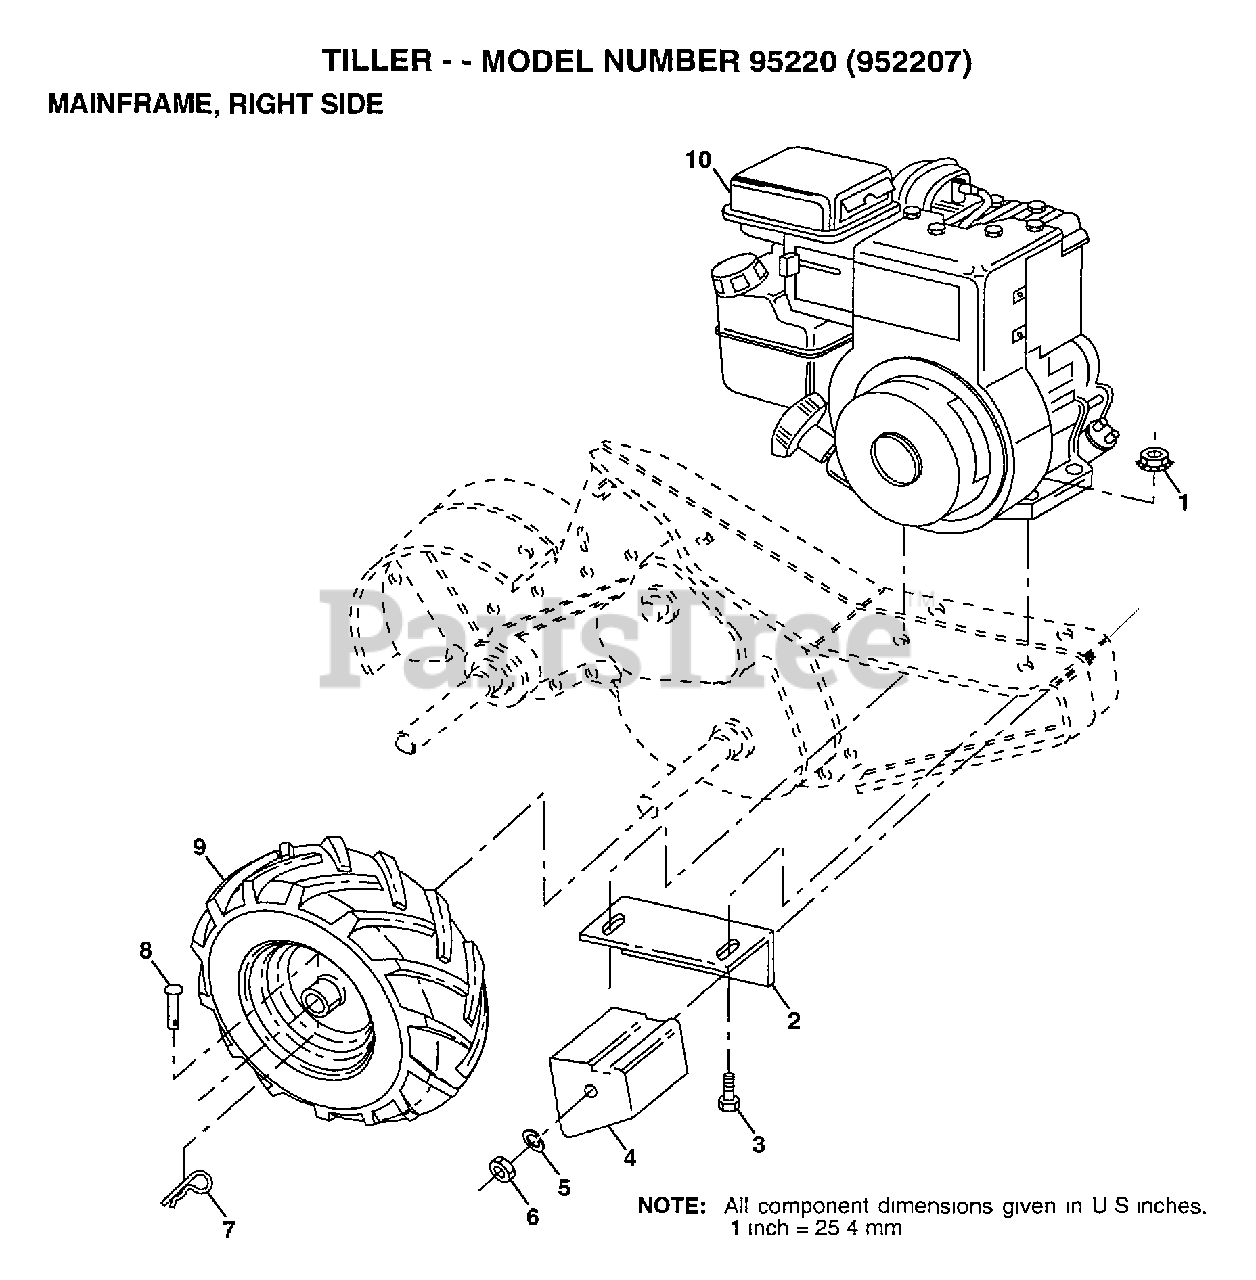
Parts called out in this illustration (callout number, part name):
1	Nut. Keps 5/16-18
2	BRACKET RH CRT
3	BOLT.HEX.5/16-1.5
4	COUNTERWEIGHT CRT
5	LOCKWASHER
6	NUT.HEX.3/8-16UNC
7	RETAINER M
8	RIVET.DRILL.1.75
9	TIRE.CHV.13X5.0-6
